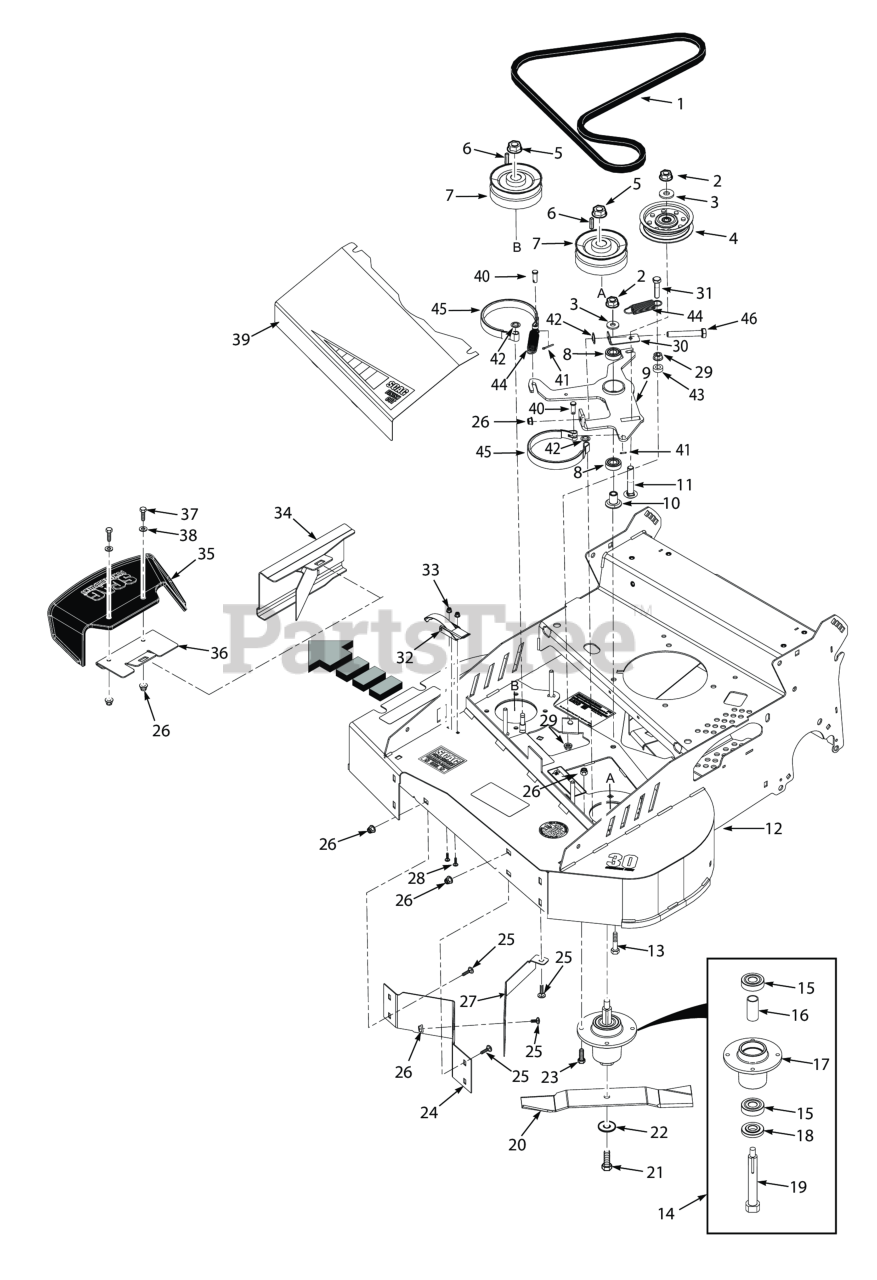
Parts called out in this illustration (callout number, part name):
1	Belt, Deck
2	Nut, Flange Elastic Stop Nut, 3/8-16
3	Flatwasher, 3/8 (.391 x .938 x .105 HD) Grade 8
4	Pulley, Idler 3-1/2"
5	Locknut, 1/2-13 Spiral Lock
6	KEY, 3/16 X 3/16 X 1-1/2
7	Pulley, Deck
8	BEARINGS, BALL, NEUTRAL RETURN
9	Idler Arm Assembly (incl. #8, #9, #26, #40, #41, #42, #45, #46, #47)
10	Pivot, Idler Short
11	SHORT SQUARE NECK CARRIAGE BOLT, 3/8-16 X 2"
12	Cutter Deck w/ Decals
13	Capscrew, Hex Head 3/8-16 x 2.0"
14	Spindle Assembly
15	Bearing
16	Spacer, Bearing
17	Housing, Spindle
18	Bearing Protector
19	Spindle Shaft
20	Cutter Blade, 15-1/4"
21	Bolt, Hex Head 1/2-13 x 1"
22	Washer, Flat, 1/2-.562 x 1.375 x .109 HD
23	Bolt, Heax Head 5/16-18 x 1" (48V / 52V)
24	Baffle, Rear Discharge
25	Bolt, 5/16-18 x .75 RHSN Carriage
26	Nut, Flange Head Elastic Stop 5/16-18
27	Baffle, Rear Discharge
28	Bolt, Carriage #10-24 x 1/2"
29	NUT, 3/8-16 SERRATED FLANGE HEX HEAD
30	Bracket, Adjustable
31	Bolt, Hex Head 3/8-16 x 1-1/2" Grade 8 Black
32	LATCH, HOOD
33	Nut, Elastic Stop #10-24
34	Weldment, Block-Off Plate
35	Discharge Chute Assembly (incl. #36, #37, #38)0
36	Mounting Bracket, Discharge Chute
37	Bolt, Heax Head 5/16-18 x 1" (48V / 52V)
38	Flatwasher, 5/16-.344 x .688 x .065 (48V / 52V)
39	Belt Cover w/Decals
40	Pin, Clevis 5/16" x 7/8"
41	Pin, Cotter 3/32 x .75"
42	Nut, Push-On 5/16-18
43	SPACER, IDLER
44	Spring, Brake
45	Brake Band
46	CAPSCREW, HEXHEAD 7/16-14 X 1.50
